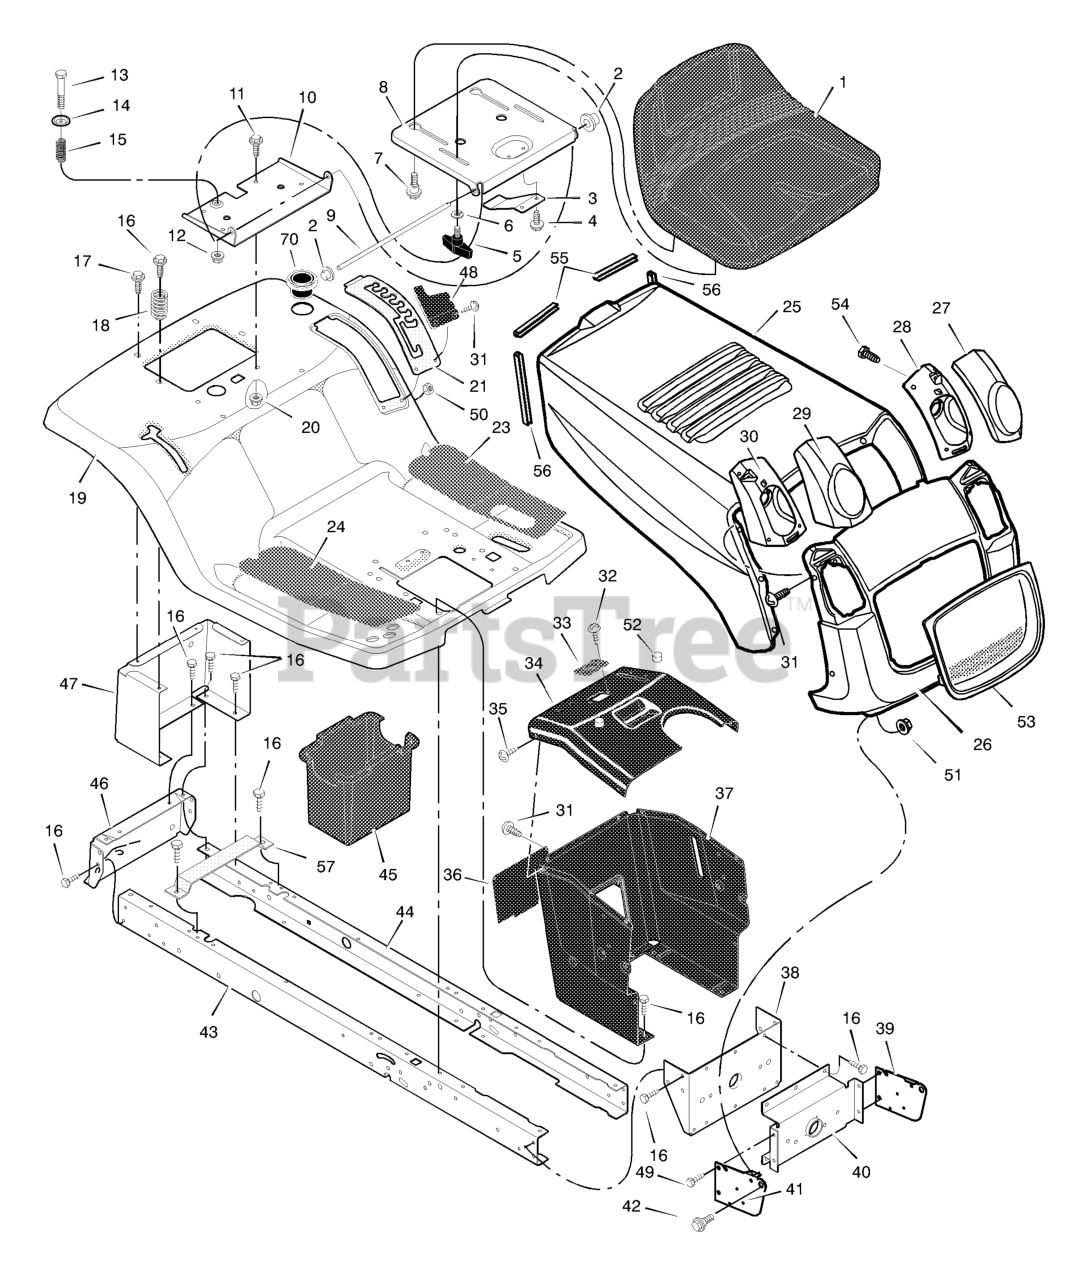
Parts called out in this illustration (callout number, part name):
1	Seat
2	Cap, Push On
5	Bolt, Wing
6	Washer
7	Bolt, Shoulder
8	Support, Seat
9	Rod, Pivot
10	Bracket, Pivot
11	Bolt
13	Bolt, Shoulder
15	Spring
19	Deck, Seat
20	Nut
21	Plate, Index
23	Mat, Left
24	Mat, Right
25	Hood
26	Grille
27	Lens, Left
28	Housing, Left Headlamp
29	Lens, Right
30	Housing, Right Headlamp
31	Screw
33	Bearing, Steering
34	Dash
36	Panel, Access
37	Support, Dash
38	Bracket, Rear Hanger
39	Support, Left Grille
40	Axle, Hanger
41	Support, Right Grille
42	Bolt, Shoulder
43	Frame, Right
44	Frame, Left
45	Container, Battery
46	Plate, Hitch
47	Panel, Rear
48	Cover, Detent
52	Bumper
53	Insert, Grille
55	Trim, Hood (3.75")
56	Trim, Hood (6.5")
57	Support, Battery
70	Holder, Cup
